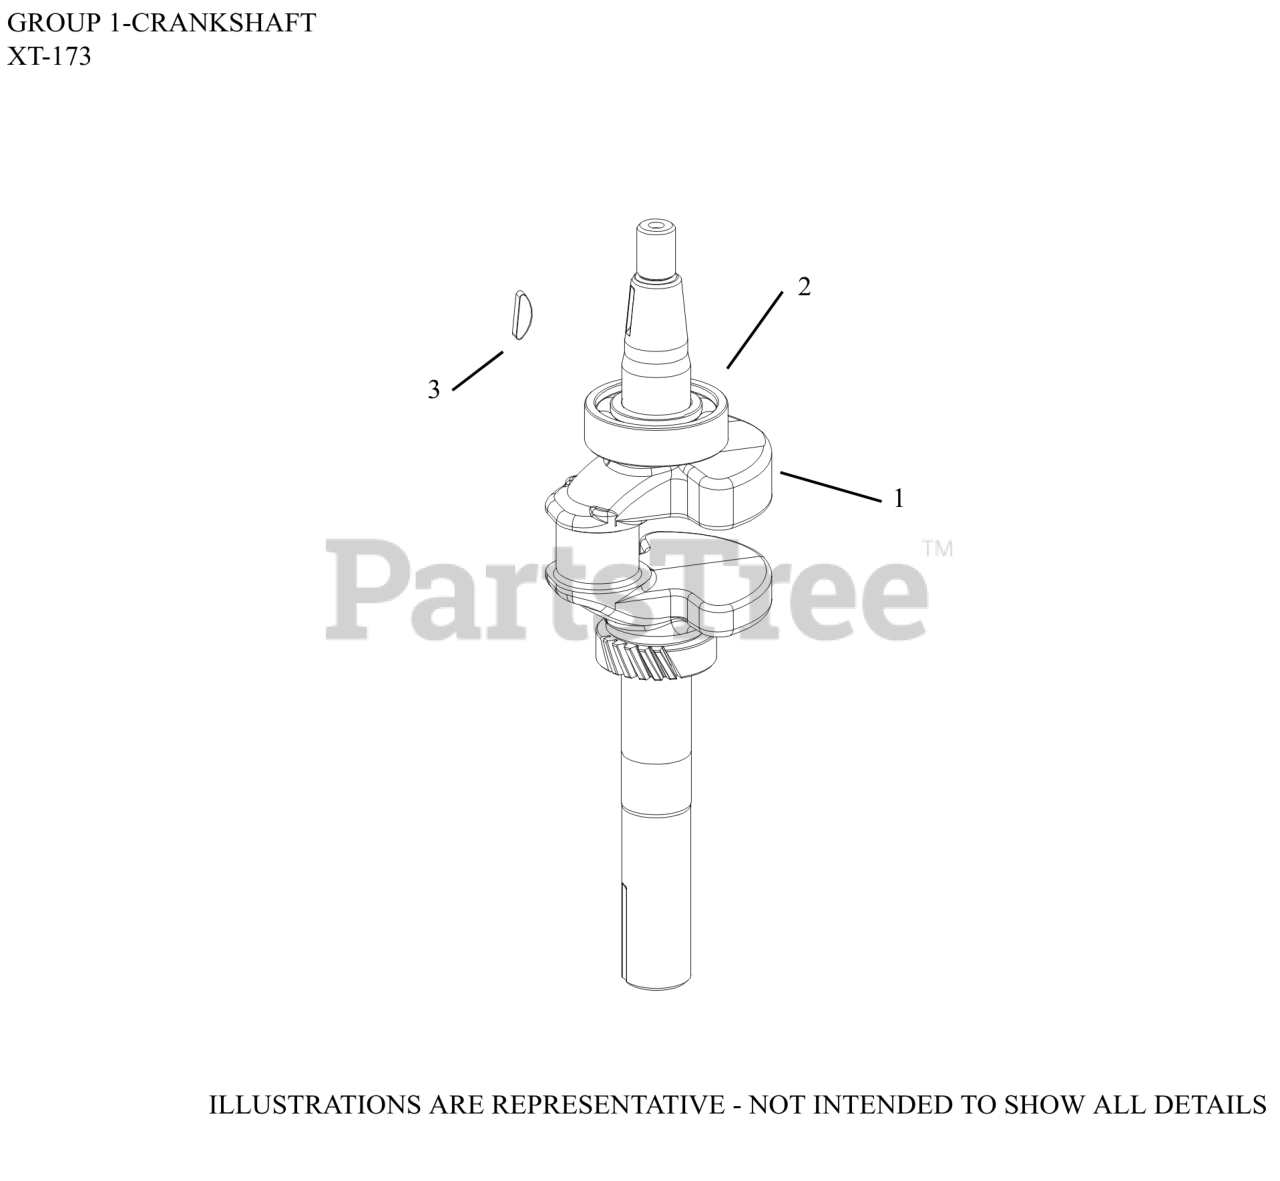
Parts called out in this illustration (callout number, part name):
1	CRANKSHAFT ASSEMBLY
2	BEARING, BALL
3	KEY, FLYWHEEL
